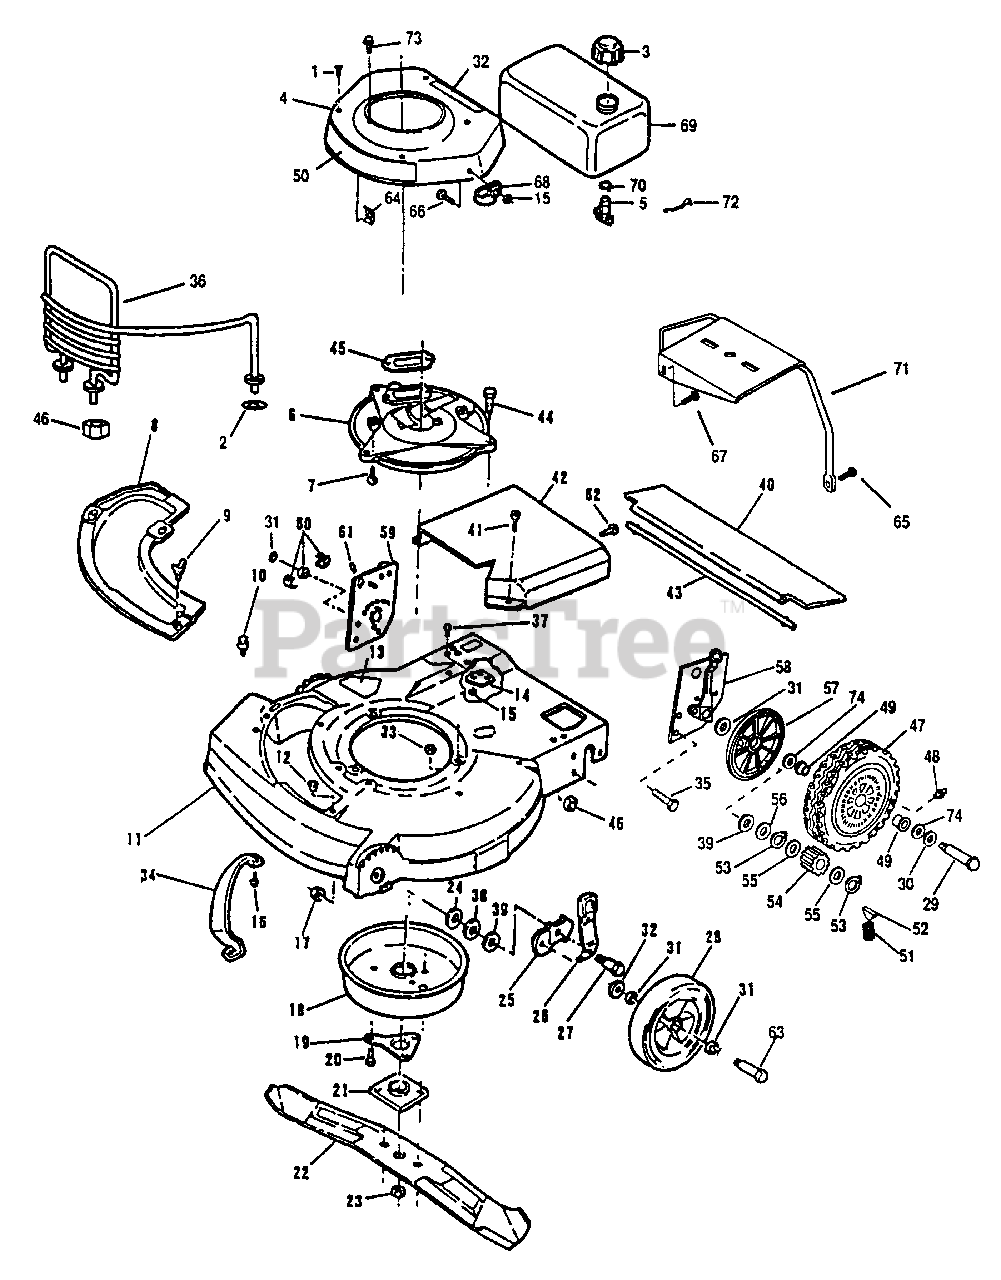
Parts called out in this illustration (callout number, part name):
1	Screw
2	Washer
3	Fuel Cap
4	Shroud-Engine
5	Valve & Screen Assembly
6	Plate Muffler
7	Screw-Muffler Plate to Block
8	Cover Plate
9	Wing Screw
10	Screw-Plate & Chute Mounting
11	Housing Assembly (Inc. 12-13)
12	Grommet
13	Decal-Blade Contact Warning
14	Bolster-Housing
15	Nut-Bolster to Housing
16	Screw
17	Nut
18	Muffler Cover Assembly
19	Support-Crankshaft
20	Screw-Muffler to Muffler Plate
21	Collar & Plate Assembly
22	Blade-21"
23	Nut-Blade
24	Washer
25	Bracket-Wheel Height Adjust
26	Knob & Spring Assembly
27	Bolt-Shoulder
28	Wheel-Front
29	Bolt-Wheel
30	Washer-Felt
31	Washer-Felt
32	Decal-Fuel Mixture
33	Nut-Muffler Plate to Housing
34	Toe Bar
35	Screw-Handle Bracket
36	Screw-Shroud to C.D. Bracket
37	Screw-Bolster to Housing
38	Washer-Shim
39	Washer-Shim
40	Shield-Trailing
41	Screw-Drive Cover Mounting
42	Cover-Drive
43	Rod-Trailing Shield
44	Screw-Muffler Plate to Housing
45	Gasket-Exhaust
46	Locknut-Hdl. Brkt. to Housing
47	Rear Wheel (Inc. 48-49)
48	Lube Fitting
49	Bushing-Wheel
50	Applique
51	Spring
52	Key
53	Retaining Ring
54	Pinion
55	Spacer
56	Washer
57	Cover-Rear Wheel
58	Height Adj Assy-L.H. (Inc. 60-61)
59	Height Adj Assy-R.H. (Inc. 60-61)
60	Bearing & Retainer Assembly
61	Fitting
62	Screw
63	Bolt
64	Retainer-Applique
65	Screw-Fuel Tank Support
66	Screw
67	Screw
68	Clamp
69	Fuel Tank
70	Clamp
71	Fuel Tank Bracket
72	Spring-Fuel Tank Mounting
73	Screw-Starter Mtg.
74	Felt Washer
